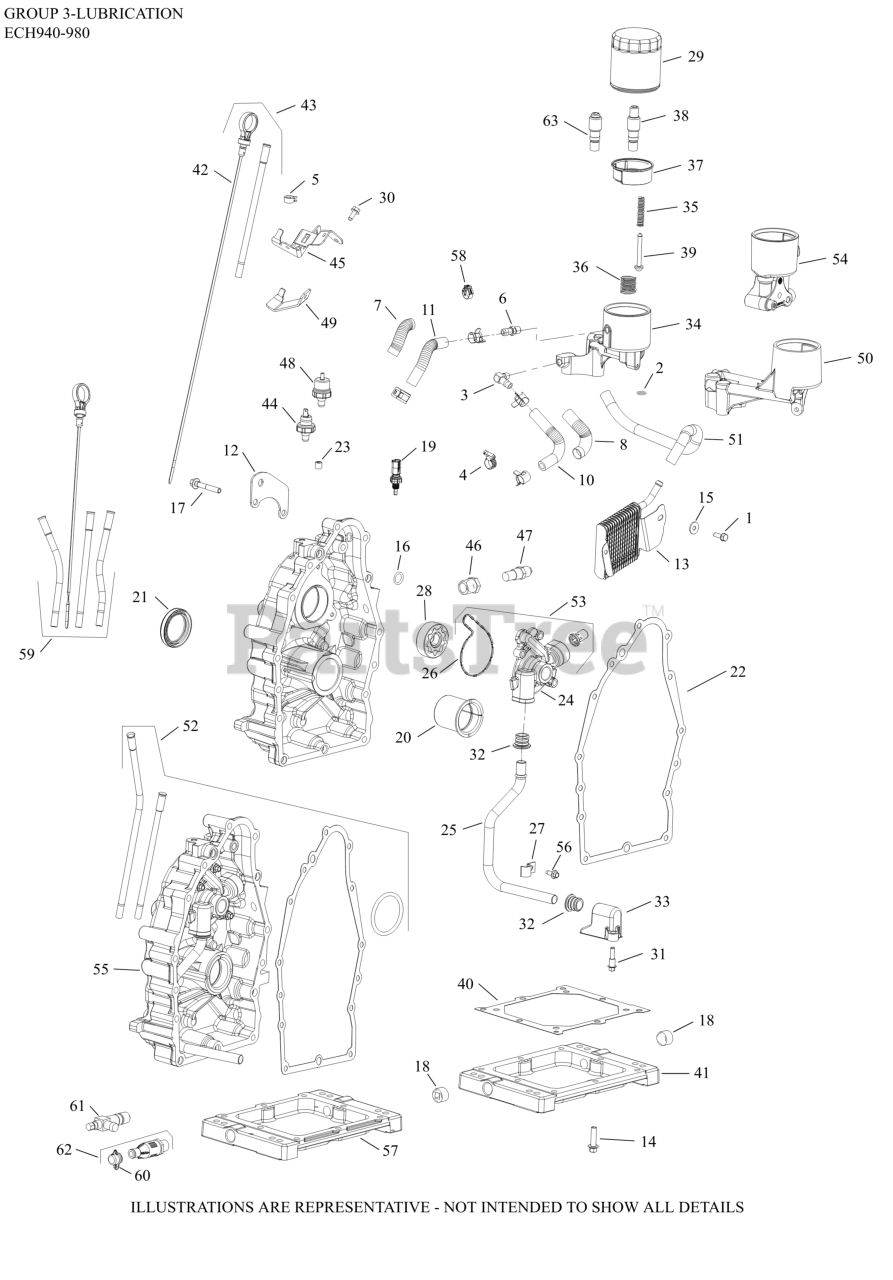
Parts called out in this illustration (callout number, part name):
1	SCREW, TAP M6X1.7X18
2	O-RING, OIL PICK-UP
3	CONNECTOR, HOSE
5	SPRING CLAMP, HOSE
6	FITTING, BARBED HOSE
7	SLEEVE, ANTI ABRASION-USE 25 431 12-S
8	SLEEVE, ANTI ABRASION-USE 25 431 12-S
9	KIT, CLOSURE PLATE-(#6200922S)
10	HOSE, OIL SUPPLY
11	HOSE, OIL RETURN
12	STRAP, LIFTING
13	COOLER, OIL ASSEMBLY
14	SCREW, FLG M8X1.25X30
15	WASHER, FLAT 1/4"
17	SCREW, HEX FLANGE
18	PLUG, PIPE 1/2 NPTF SQ CTSK
19	SENSOR, TEMPERATURE
20	BEARING, CRANKSHAFT (PTO)
21	SEAL, OIL
22	GASKET, OIL PAN
23	PLUG, CTSK PIPE 1/8"
24	HOUSING, OIL PUMP MACH-USE 62 081 38-S
25	TUBE, OIL PICK-UP
26	O-RING, OIL PUMP HOUSING
28	PUMP ASSEMBLY, OIL/GEROTOR
29	OIL FILTER
31	SCREW, SHD THD FRM M6X.0X6.5
32	SEAL, PICK-UP TUBE
33	HOUSING, OIL PICK-UP ASSEMBLY
34	KIT, OIL FILTER HOUSING
35	SPRING, OIL FILTER VALVE
36	SPRING, OIL FILTER CUP
37	CUP, OIL FILTER ASSEMBLY
38	NIPPLE, OIL FILTER ASSEMBLY-(#6213606S)
39	VALVE, OIL FILTER
40	GASKET, OIL RESERVOIR
41	TUBE, OIL PICK-UP
44	SWITCH, OIL PRESSURE
45	BRACKET, FUSE HOLDER
56	SCREW, THREAD FORMING
57	OIL RESERVOIR
58	CLAMP, HOSE OETIKER
NI	SCREW, HEX FLANGE M6 X 1
